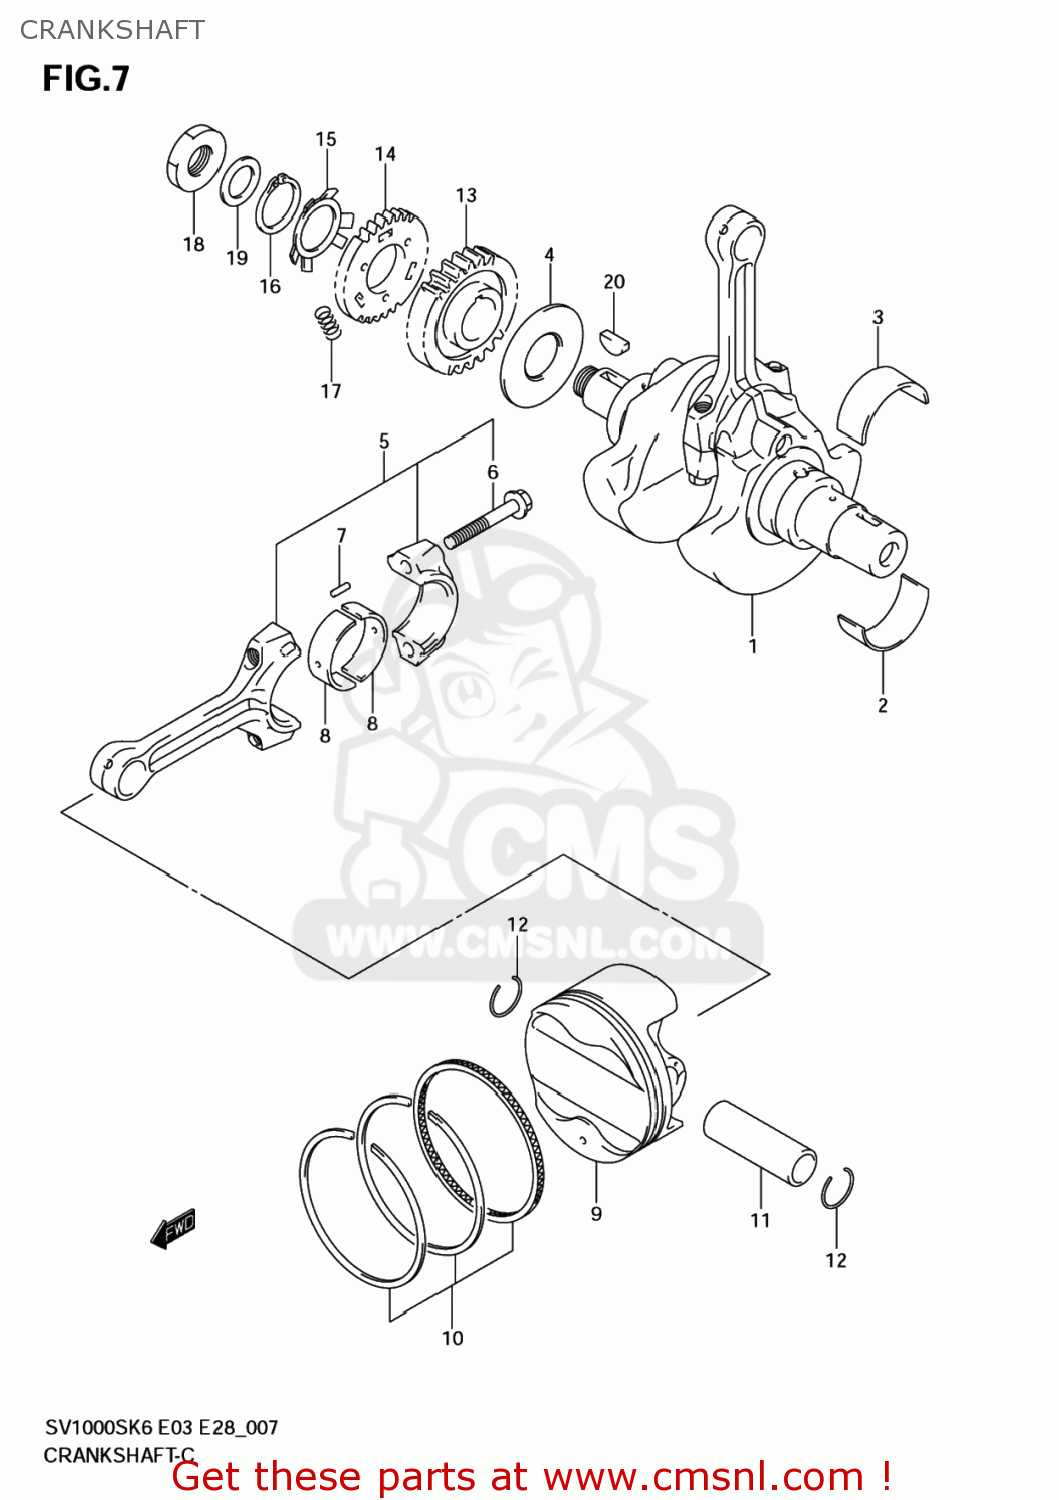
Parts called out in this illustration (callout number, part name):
1	CRANKSHAFT
2	BEARING,CRANKSHAFT
3	BEARING,CRANKS
4	WASHER,CRANK THRUST
5	CONNECTING ROD ASSY
6	BOLT,CONNECTING ROD
7	PIN,CONNECTING ROD
8	BEARING,CRANK PIN
9	PISTON
10	RING SET,PISTON
11	PIN,PISTON
12	CIRCLIP
13	GEAR,PRIMARY DRIVE
14	GEAR,PRIMARY DRIVE SCISSORS
15	WASHER,PRI DRIVE
16	CIRCLIP
17	SPRING
18	NUT
19	WASHER
20	KEY
